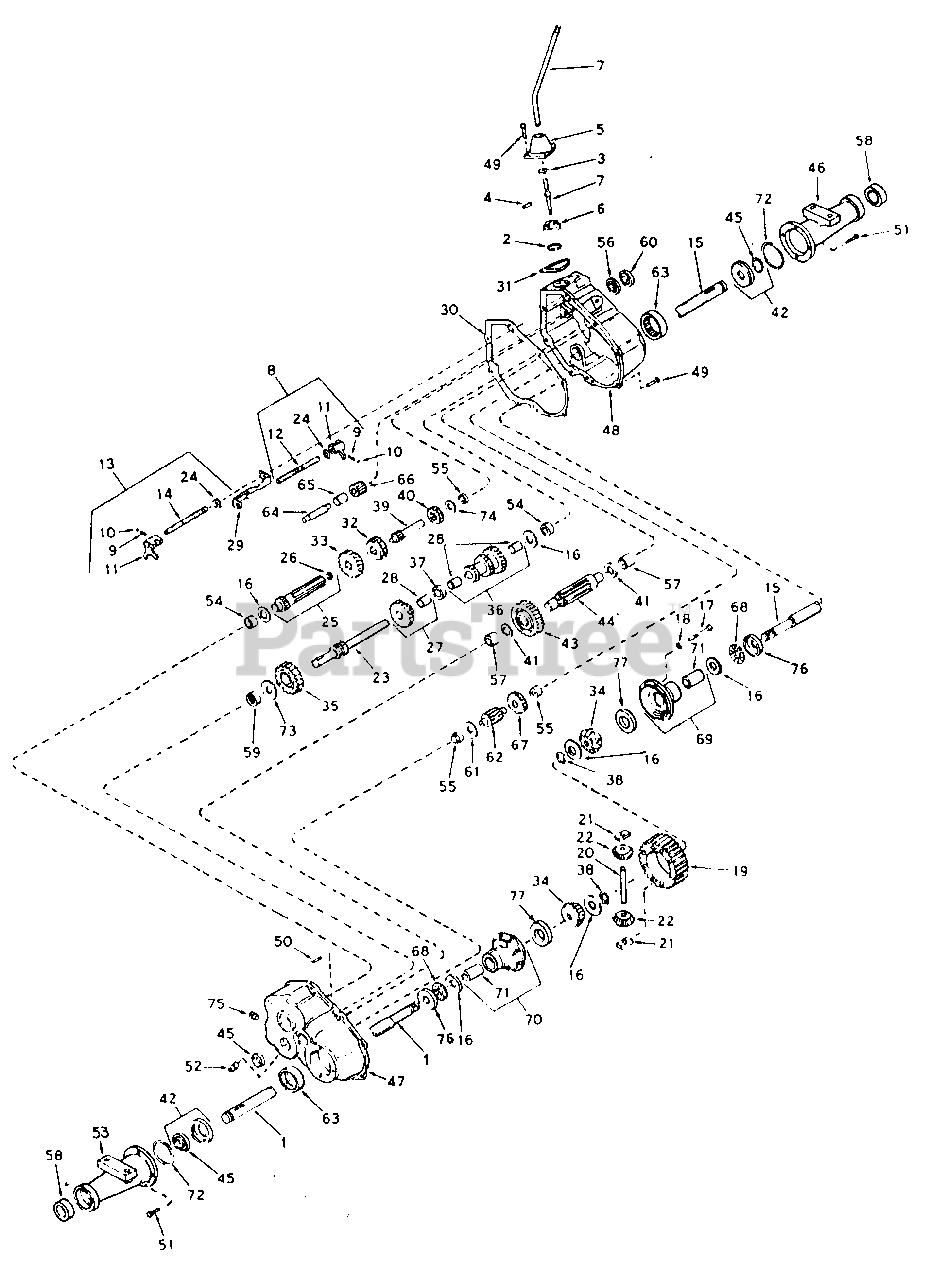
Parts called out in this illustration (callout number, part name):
2	Ring, Snap
3	Ring, Quad
5	Housing, Shift Lever
6	Retainer, Shift Lever
7	Lever, Shift
8	Rod Assy, Shift
10	Ball, Steel
11	Fork, Shifter
12	Rod, Shifter 3rd & 4th
13	Rod Assy, Shift
14	Rod, Shifter 1st & 2nd
16	Washer, Thrust
17	Bolt, 1/4 X 2-1/2 Pln Type 8
18	Washer, 1/4 Heavy Lock
20	Pin, Drive
21	Block, Drive
22	Pinion, Bevel
23	Shaft, Brake Gear
24	Ring, Snap
25	Shaft Assy, Pinion
26	Bearing Assy, Needle
27	Gear Assy, Cluster
29	Stop, Shifter
30	Gasket, Case to Cover
31	Gasket, Shifter Lever Housing
32	Gear, Shift 3rd & 4th
33	Gear, Shifting 1st, 2nd & Reverse
34	Gear, Bevel
35	Gear, Idler
36	Gear, Cluster
38	Ring, Snap
39	Shaft, Input
40	Gear, Input Shaft Spur
41	Washer, Thrust
42	Retainer Assy, Oil Seal
43	Gear, Output
44	Pinion, Output
46	Housing, Axle RH
47	Cover Assy, Transaxle
48	Case Assy, Transaxle
49	Screw, 1/4-20 X 3/4 Flanged
50	Pin, Dowel
51	Bolt, 5/16 X 1 Pln Type 5
52	Plug, Magnetic Drain
53	Housing, Axle LH
54	Bearing, Needle
55	Bearing, Needle
56	Bearing, Ball
57	Bearing, Needle
58	Bearing Assy, Ball
59	Bearing, Needle
62	Shaft, Pinion
63	Bearing, Needle
64	Shaft, Reverse Idler
65	Spacer, Reverse Idler
66	Idler, Reverse
67	Gear, Spur -22T
68	Bearing, Thrust
69	Carrier Assy, Differential RH
70	Carrier Assy, Differential LH
71	Bushing, Carrier
73	Washer, Thrust
74	Washer, Thrust
75	Plug, Pipe
76	Bearing, Thrust Race
